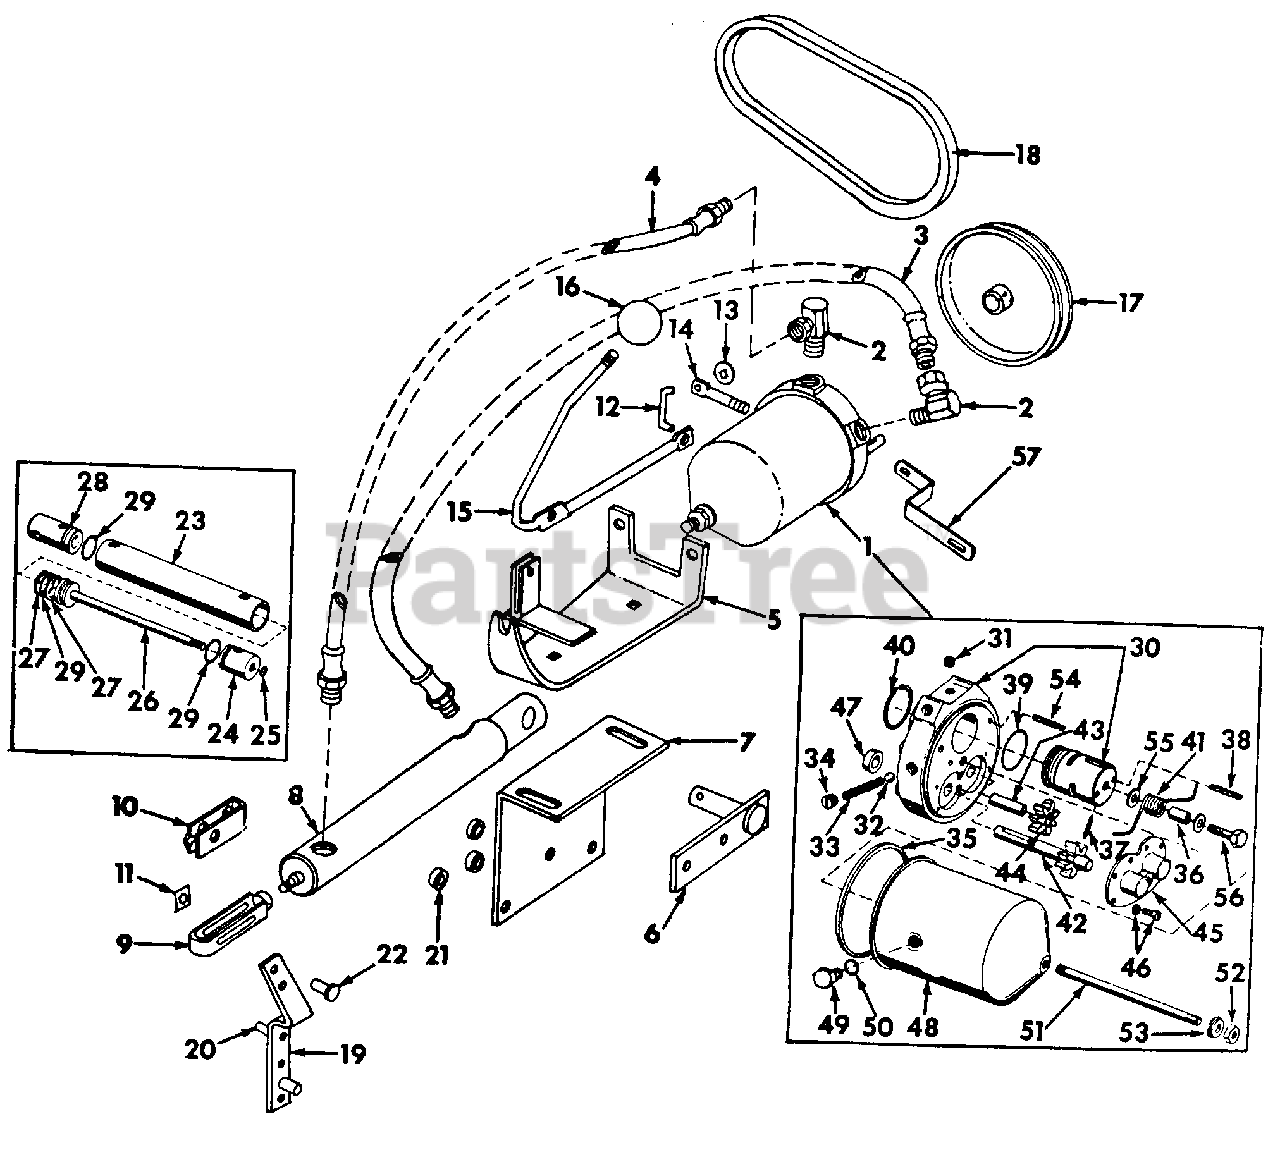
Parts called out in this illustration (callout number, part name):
1	Pump Assy, Hyd
2	Fitting, Hyd Pump 90 Deg Union
3	Hose Assy, Hyd 9 In.
4	Hose Assy, Hyd 14 In.
5	Bracket Assy, Hyd Pump Mounting
6	Bracket Assy, Hyd Cyl Support
7	Bracket, Frame Mounting
8	Cylinder Assy, Hyd
9	Clevis Assy, Hyd Cyl End
10	Clip, Cyl End Clevis Rivet Locking
11	Nut, Locking Clip Push-On Type
12	Rod, Hyd Pump Actuator Control
13	Nut, Actuator Control Rod Push-On Type
14	Extension, Pump Spool
15	Rod, Control Lever
16	Knob, Control Lever Rod
17	Pulley, Driven
18	Belt, Drive Pulley
19	Arm Assy, Lift
20	Pin, 5/16 X 3/4 Dowel
21	Spacer, Frame Mounting Bracket
22	Rivet, 1/2 X 1-1/4 F-Hd Solid
23	Tube, Hyd Cyl
24	Guide, Hydraulic Cylinder
25	O-Ring, 5/8 X .813 X 3/32
26	Piston & Rod, Hydraulic Cylinder
27	Washer, Piston & Rod Backup
28	Head, Hyd Cylinder
29	O-Ring, 1-1/4 X 1-1/2 X 1/8
30	Body & Valve, Hyd Pump
31	Plug, 1/8-27 Automotive Hex Soc Hd Pipe
32	Ball, 5/16 Cr-Stl
33	Spring, Hyd Pump Body
34	Plug, Pump Body Spring Retaining
35	Gasket, Hyd Pump Body
36	Spacer, Spring Sleeve
37	Pin, 5/32 X 7/8 Slt Spring
38	Pin, 1/8 X 1-1/4 Slt Spring
39	O-Ring, 1-1/4 X 1-1/2 X 1/8
40	Ring, Hyd Pump Spool Valve Snap
41	Spring, Hyd Pump Spool Valve
42	Shaft Assy, Hyd Pump Drive
43	Shaft, Hyd Pump Idler
44	Gear, Hyd Pump Idler Shaft
45	Cover, Hyd Pump Shaft
46	Screw w/Spring Lock Washer, 10-13 X 7/16 Slt Fil Hd Mach
47	Seal, Hyd Pump Drive Shaft
48	Reservoir, Hyd Pump
49	Screw, 1/2-20 X 1/2 Hex Hd Cap
50	Washer, Hyd Pump Reservoir Fiber
51	Stud, Hyd Pump Reservoir
52	Nut, 3/8-16 Hex Jam
53	Washer, Hyd Pump Reservoir Stud
54	Pin, 3/16 X 1-1/2 Slt Spring
55	Washer, 11/32 X 11/16 X .065
56	Screw w/Nylon Pellet, 5/16-18 X 1-1/8 Hex Hd Cap
57	Arm, Support
